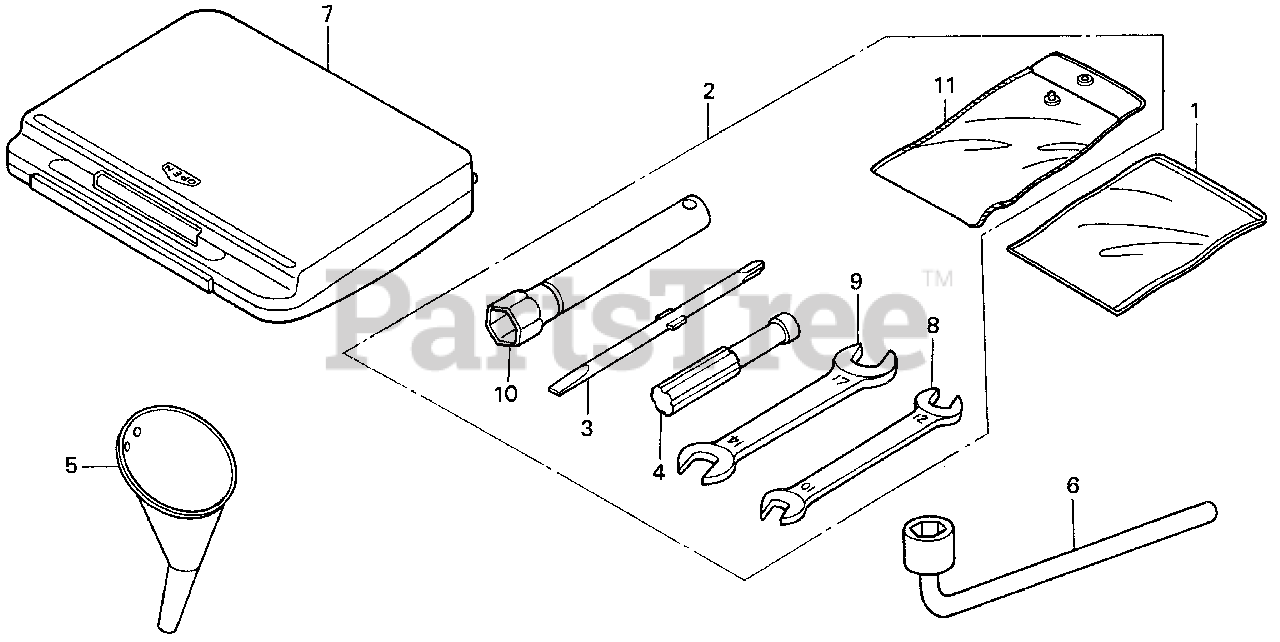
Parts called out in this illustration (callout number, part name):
1	BAG, OWNER'S MANUAL
3	SHAFT, SCREWDRIVER
5	FUNNEL, OIL
6	WRENCH, WHEEL NUT
8	WRENCH (10X12) (OPEN END)
9	WRENCH (14X17) (OPEN END)
10	WRENCH, BOX (P21)
